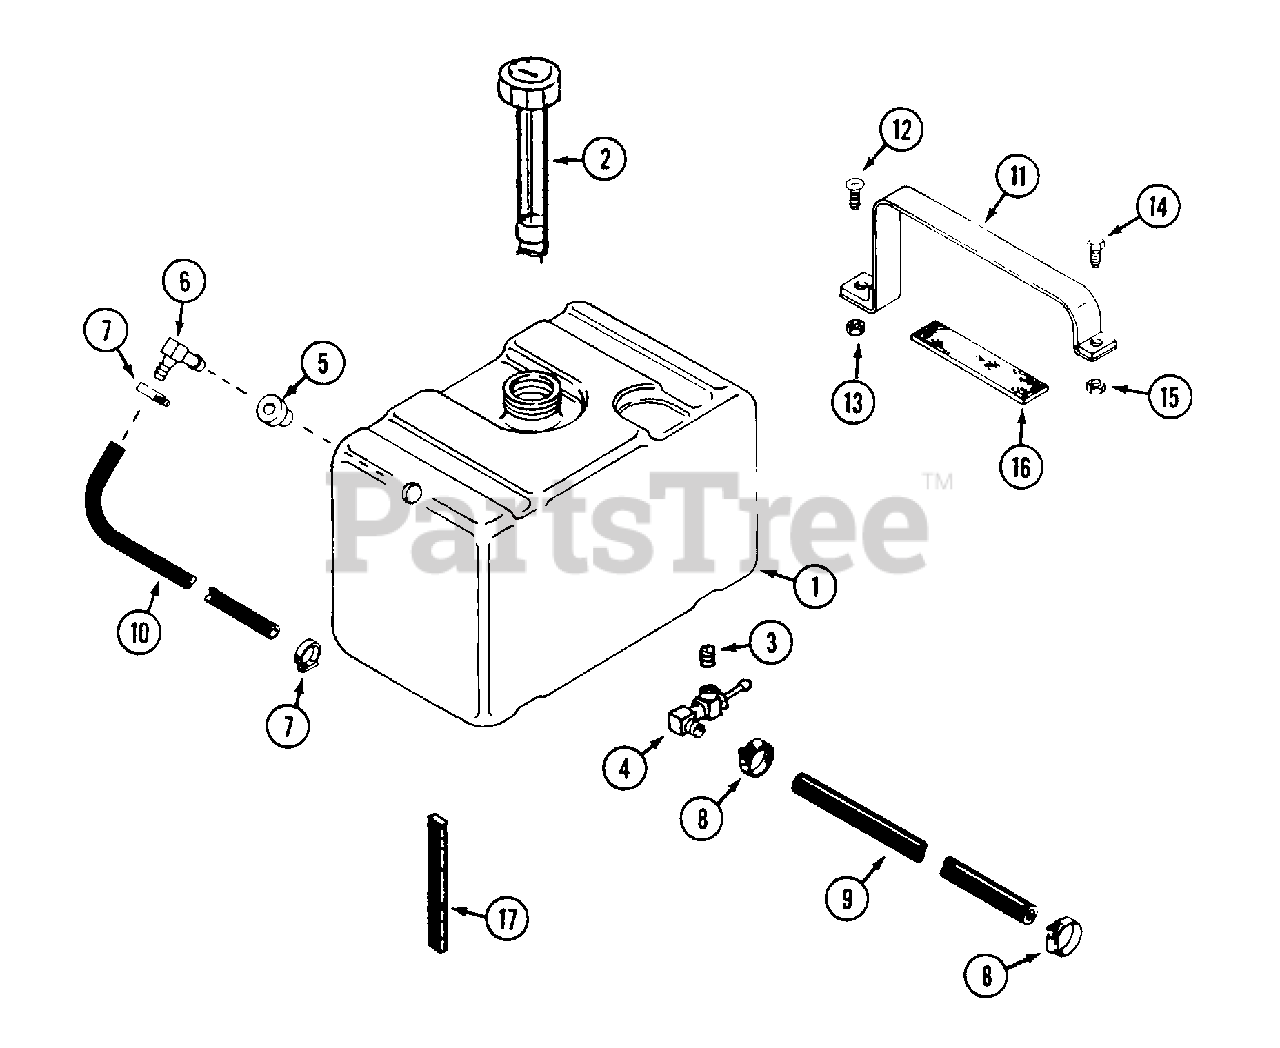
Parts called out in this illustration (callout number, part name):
1	TANK - fuel
2	CAP - fuel gauge
3	NIPPLE - pipe 1/8"
4	FITTING - valve 1/8" x 904
5	GROMMET - tank
6	FITTING - return 90°.
7	CLAMP - hose #4
8	CLAMP - hose #8
9	HOSE - fuel 1/4" x 45"
10	HOSE - return 3/16" x 51"
11	STRAP - fuel tank
12	BOLT - 5/16" - 18 x 1"
13	NUT - 5/16" - 18 lock
14	BOLT - 1/4" - 20 x 3/4"
15	NUT - 1/4" - 20 lock
17	FOAM - tank cushion
